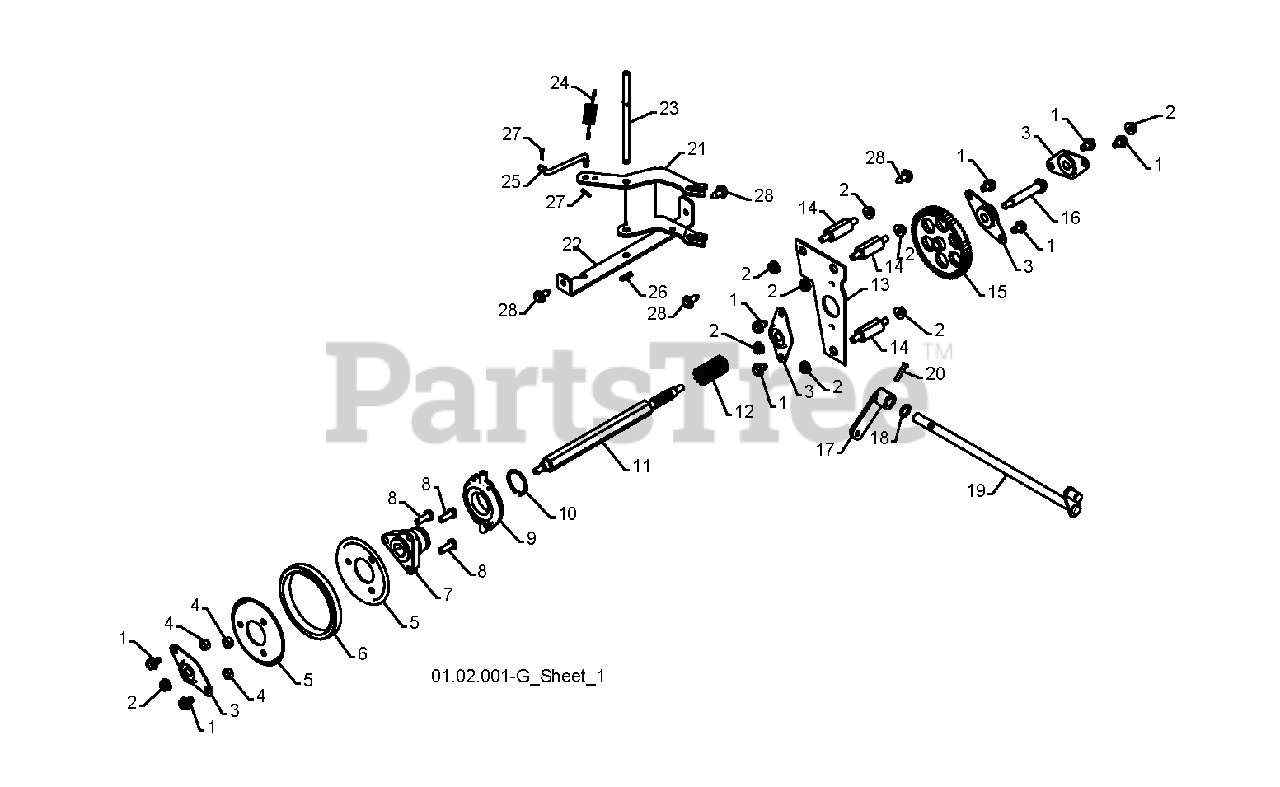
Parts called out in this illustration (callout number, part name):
2	NUT, LOCK 5/16-18
3	BEARING, FLANGE
4	NUT.CENTERLOCK.5/16-
5	PLATE.RUBBER.WHEEL
6	RING, RUBBER WHEEL
7	HUB, RUBBER WHEEL
9	TRUNNION BEARING ASSY
10	RETAINING RING
11	SHAFT.HEX.LONG
12	GEAR, PINION
13	AUXILLARY PLATE
14	SPACER, PLATE
15	GEAR, INTERMEDIATE
16	SHAFT, AUXILIARY
17	ARM, AUGER CONTROL
18	THRUST WASHER
19	SHAFT, AUGER CONTROL
20	CLEVIS PIN
21	LEVER, SPEED CONTROL
22	BRACKET, PIVOT, SHIFT
23	PIN, PIVOT
24	SPRING, BIAS
25	LINK, SPEED CONTROL
26	RETAINER CLIP PM
27	RETAINER CLIP
28	BOLT.HEX.HD.WASHER.5/16-18X.75
